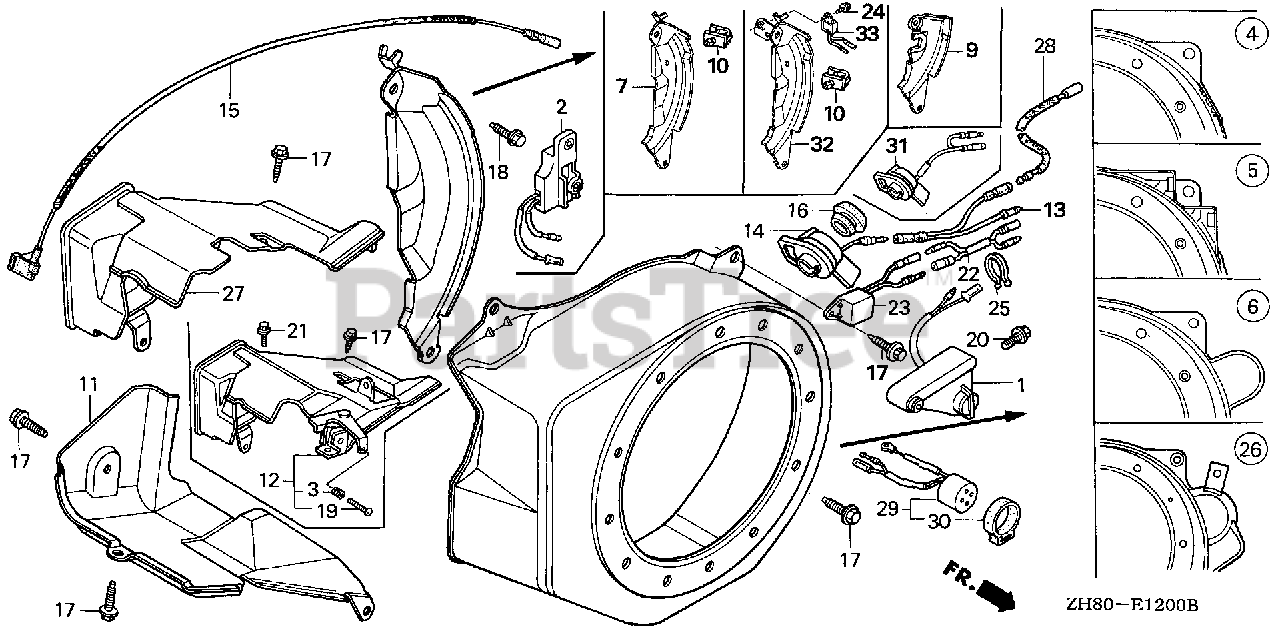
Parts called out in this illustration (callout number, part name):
4	COVER, FAN *R280* (POWER RED)
7	PLATE, SIDE (OIL ALERT)
10	CLAMP, CORD
10	CLIP, HARNESS
13	SUB-HARNESS
14	SWITCH ASSY., ENGINE STOP
17	BOLT, FLANGE (6X12) (CT200)
18	BOLT, FLANGE (6X20) (CT200)
24	BOLT, FLANGE (6X8)
32	PLATE, SIDE (OIL ALERT)
33	ALERT UNIT, OIL
